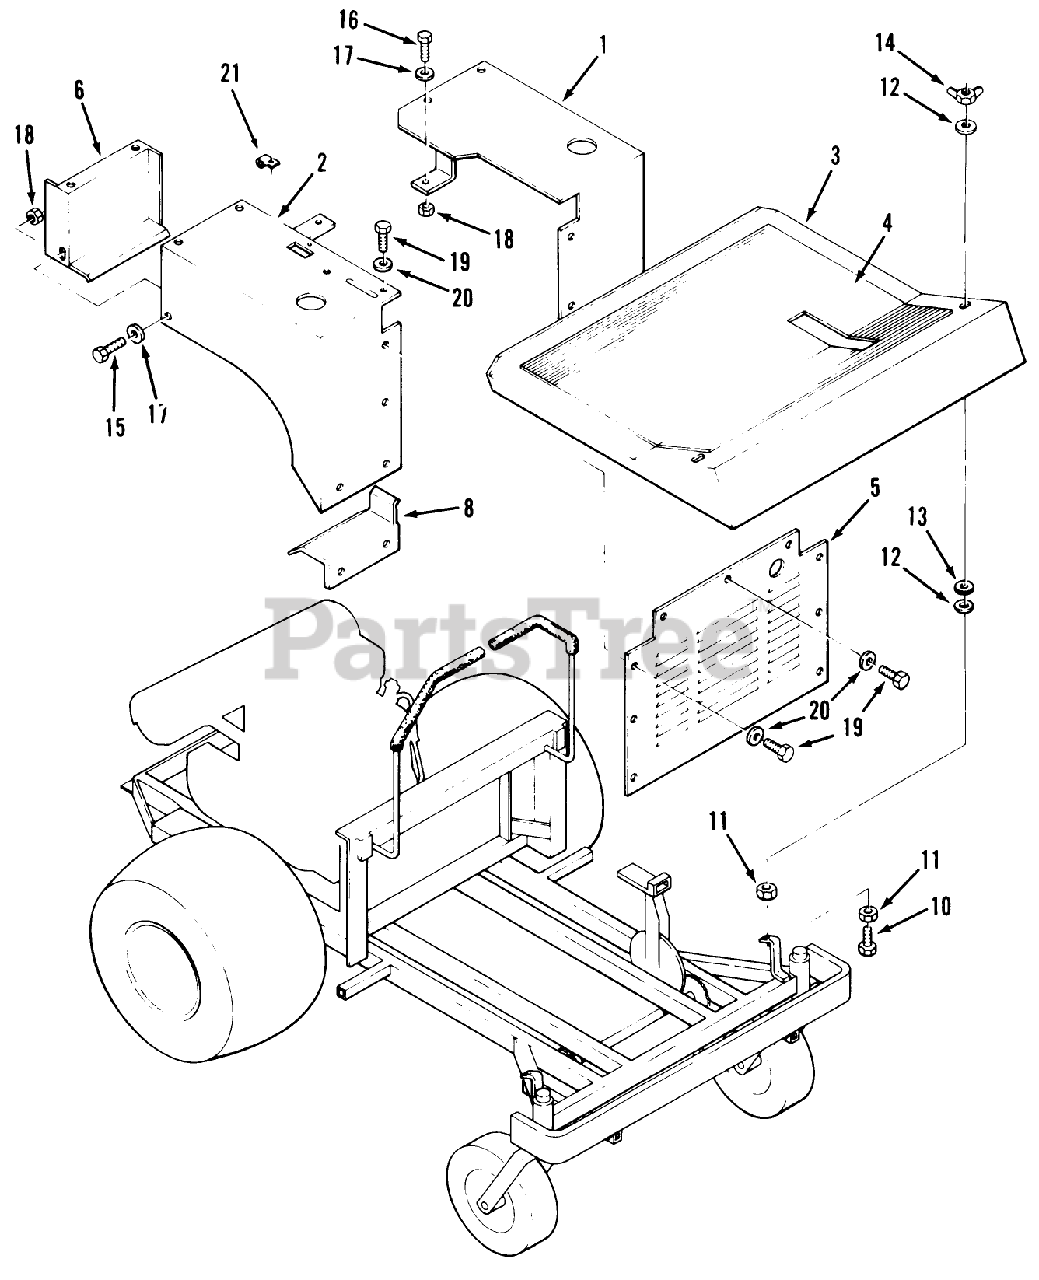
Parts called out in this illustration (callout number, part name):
1	Fender LH
2	ASS'Y-FENDER R.H. R
3	Floor Pan
4	Black Carpet
5	Front Panel
6	Bracket-Fender Rear RH
8	Bracket-Fender Frt RH
10	Full Thread Bolt 5/16 x 1-1/2
11	Nut
12	Washer
13	WASHER
14	WING NUT
15	H H C S
16	Bolt
18	Nut
19	Bolt
20	WASHER
21	J-CLIP
